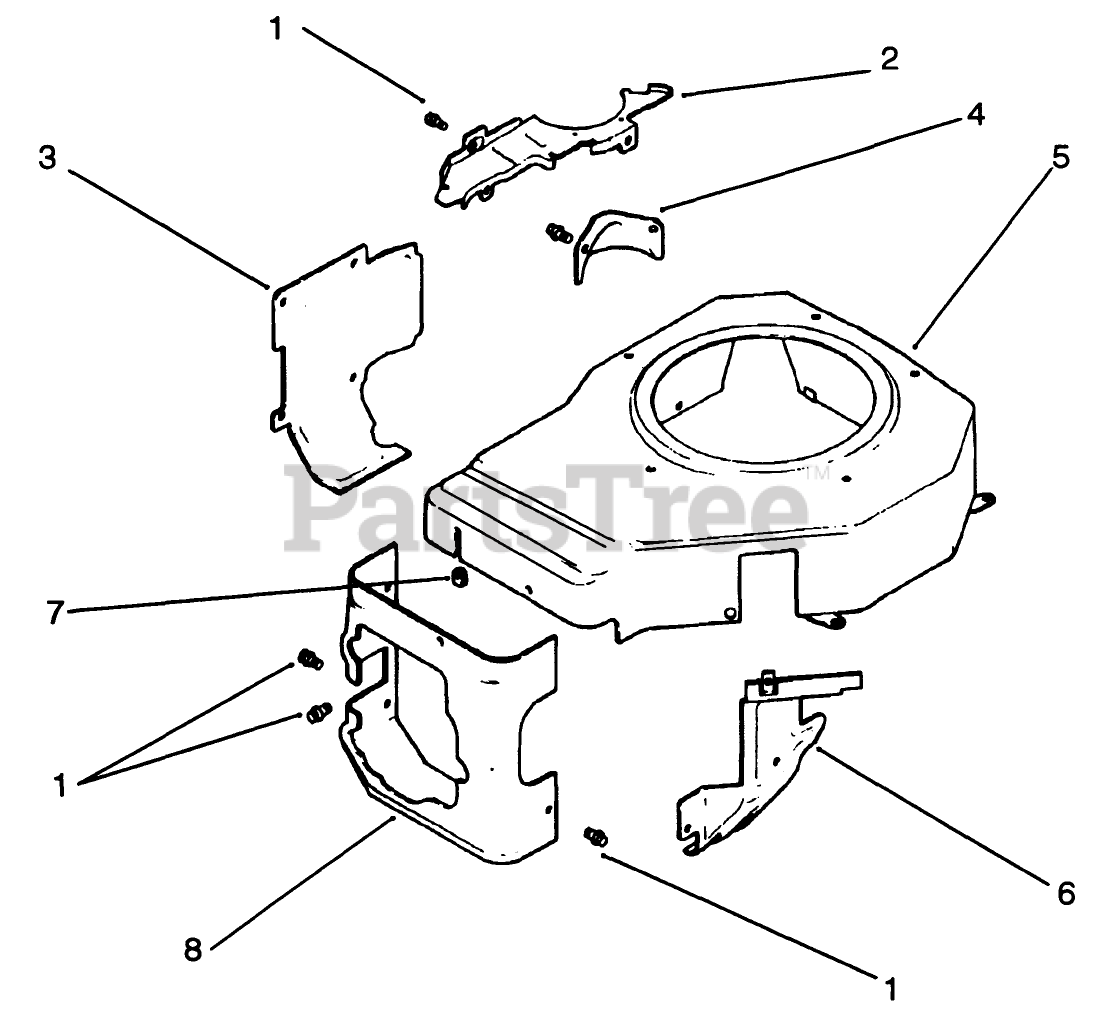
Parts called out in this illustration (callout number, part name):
2	Plate-Blower Housing (Only On: 72042,72043,72062,72063)
3	Baffle-Cylinder Barrel (Only On: 72042, 72063, 72062, 72043)
4	Cover-Starter
5	Cover-Housing
6	Baffle-Carburetor (Only On: 72042, 72043, 72062, 72063)
7	Grommet-Blower Housing (Only On: 72042, 72043, 72062, 72063)
8	Baffle-Cylinder Head
